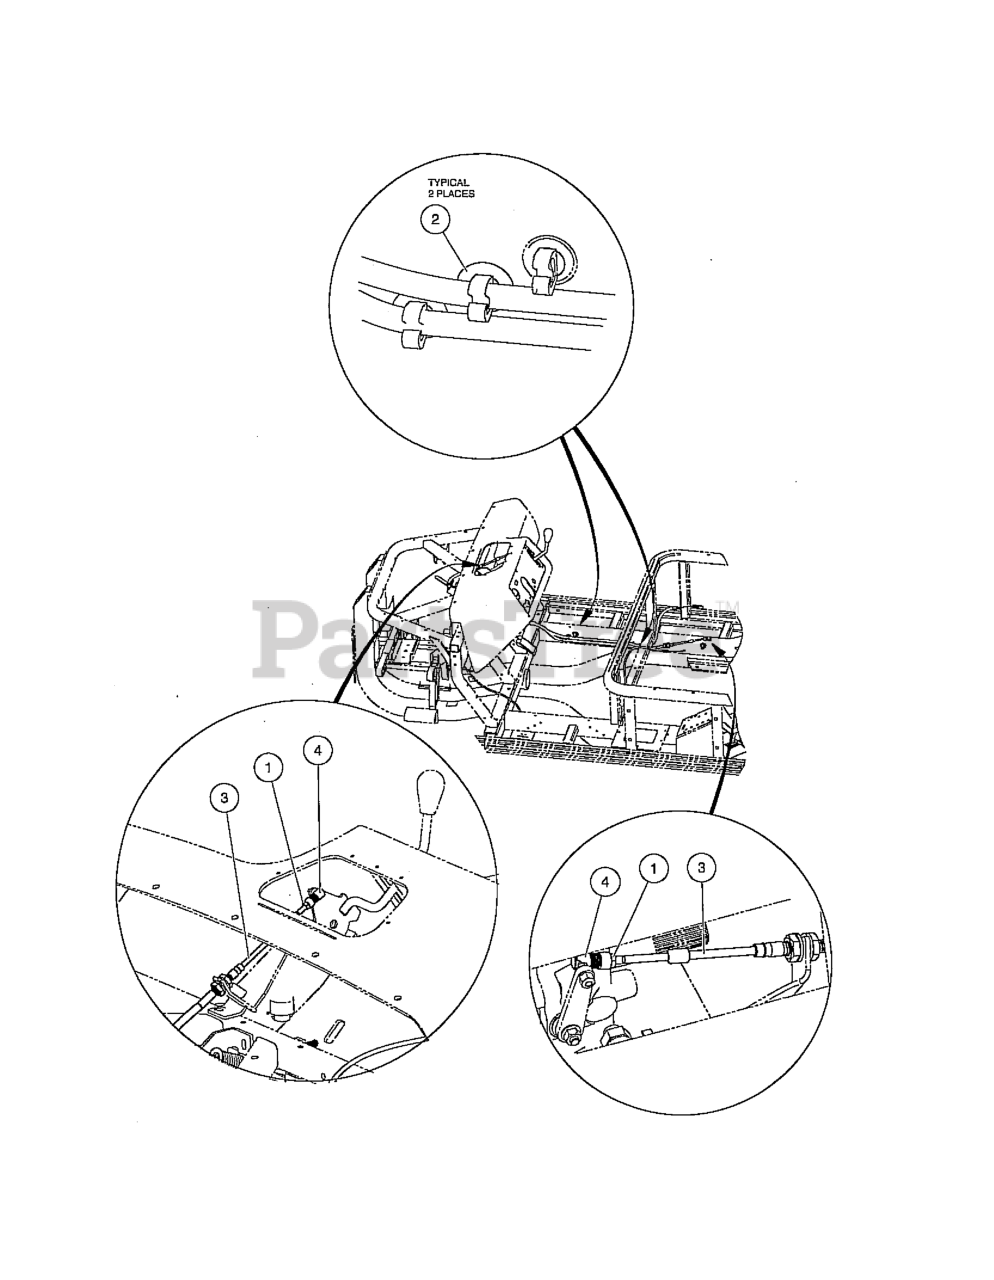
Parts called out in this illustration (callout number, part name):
2	CLIP, BRAKE LINE
3	CABLE, TRANSMISSION SHIFT, AWD
4	JOINT, BALL, .346 DIA
